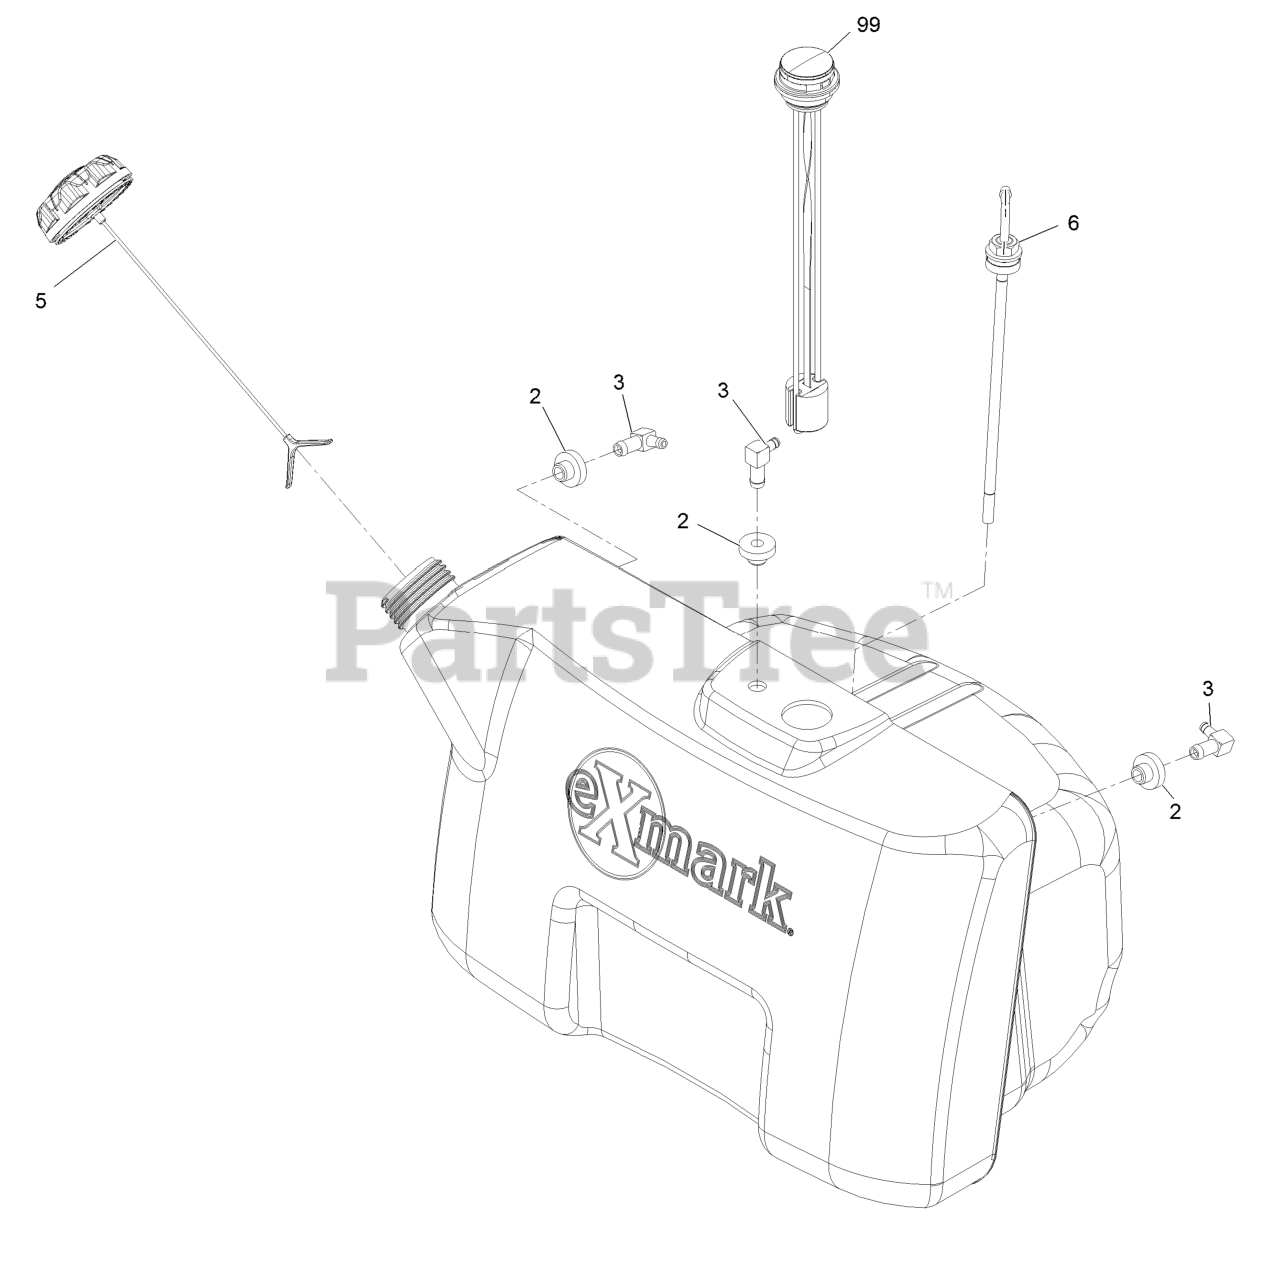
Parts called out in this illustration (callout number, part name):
2	Bushing
3	Elbow-90 DEG
5	Cap-Fuel, Ratcheting
6	Fitting-Fuel, Bulkhead
99	Kit, Fuel Gage Replacement
